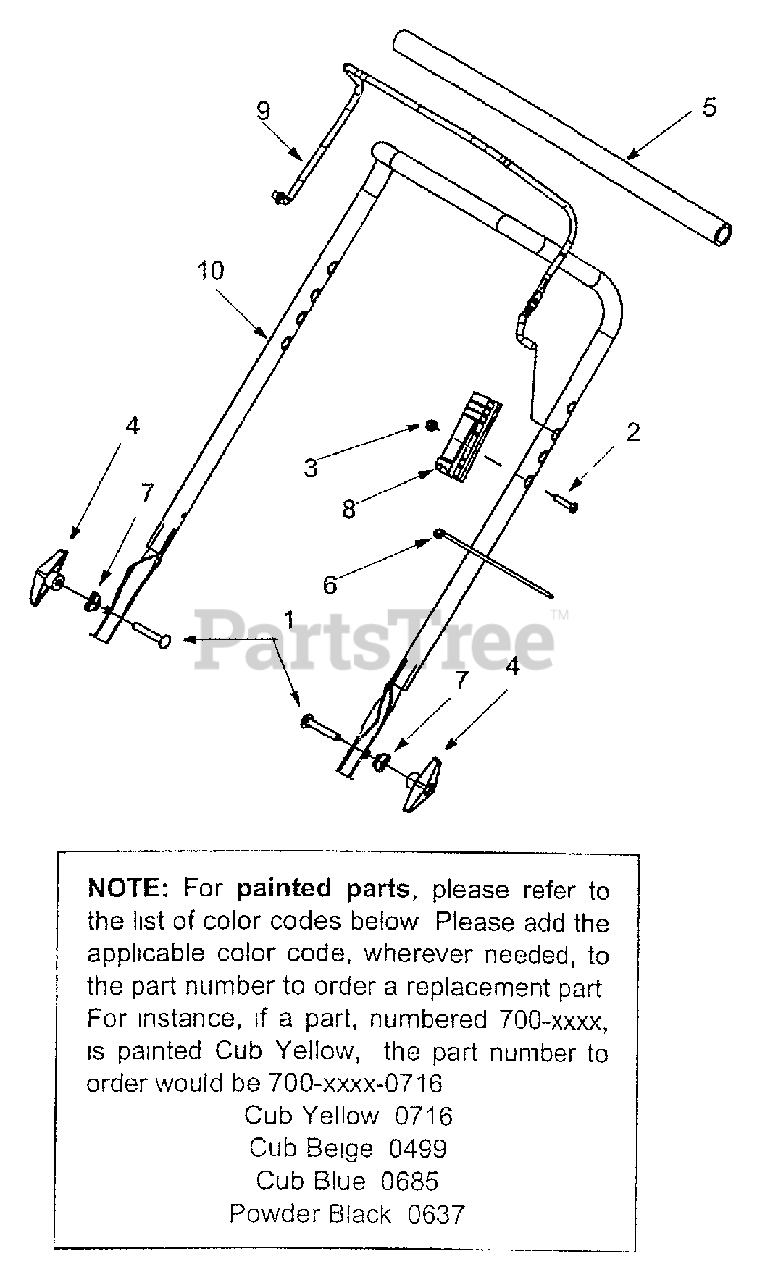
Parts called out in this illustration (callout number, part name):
1	Carriage Screw
2	Oval C-Sunk Machine Screw
3	Hex Lock Nut
5	Foam Grip: Handle
6	Cable Tie
7	Saddle Washer
8	Cable Housing w/o Throttle
